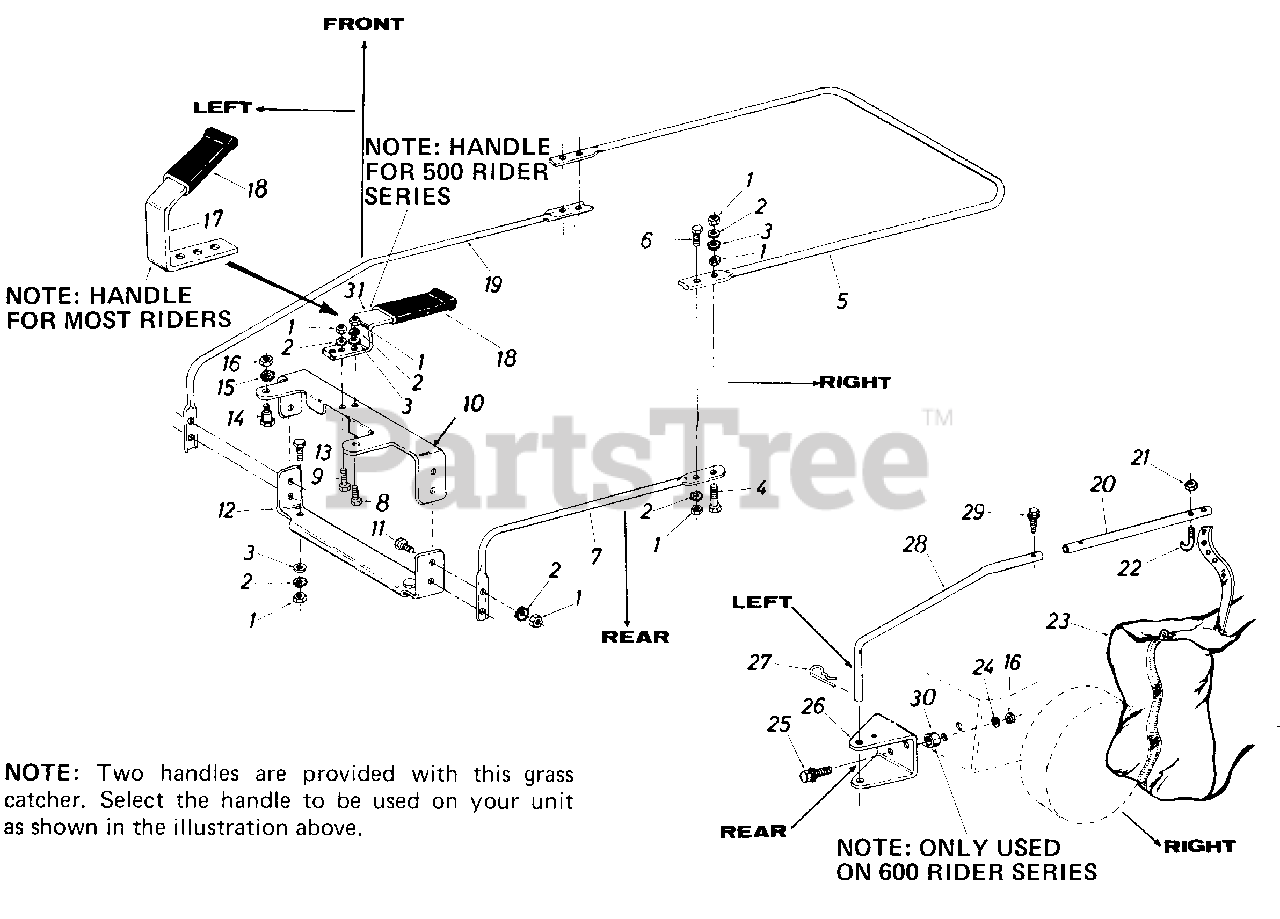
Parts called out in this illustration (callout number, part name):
1	Hex Nut 1/4-20 Thd.*
2	Ext. L-Wash. 1/4" Scr.*
3	Fl-Wash. .281 I.D. x .50 O.D.
4	Hex Scr. 1/4-20 x 1.50" Lg.*
5	Upper Frame Half
6	Hex Scr. 1/4-20 x 1.00" Lg.*
7	Lower Frame Tubing
8	Hex Scr. 1/4-20 x .75" Lg.
9	Hex Scr. 1/4-20 x .75" Lg.*
10	Upper Opening Support
11	Hex Scr. 1/4-20 x 1.0" Lg.*
12	Lower Opening Support
13	Hex Scr. 1/4-20 x .50" Lg.*
14	Shld. Scr. .437 Dia. x .350
15	Ext. L-Wash. 5/16" Scr.*
16	Hex Nut 5/16-18 Thd.*
19	Lower Frame Arm
23	Grass Catcher Bag
24	L-Wash. 5/16" I.D.*
25	Hex Sems Scr. 5/16-18 x .75" Lg.*
26	Hitch Bracket
27	Internal Cotter Pin 5/8" Dia.
28	Lower Holding Arm
29	Hex Wash. Hd. Self-Tap .50" Lg.
30	Spacer
31	Handle
